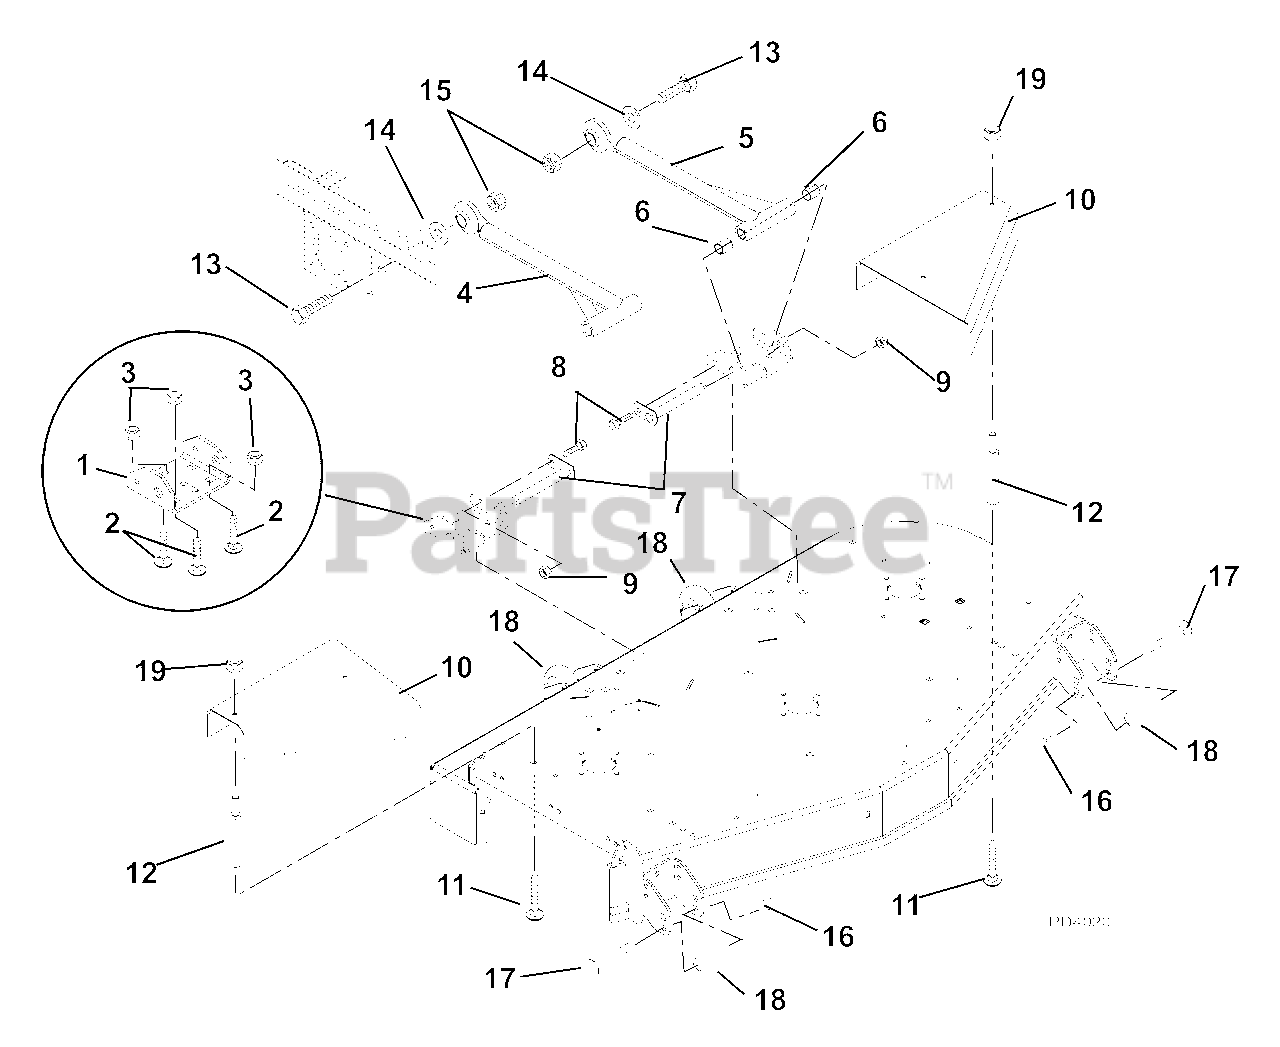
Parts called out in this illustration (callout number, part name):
1	Bracket, Mower Mounting (Rear)
2	Bolt, Round Head Square Neck .50-13 x .75 Grade 5
3	Nut, Locking Center Jam .50-13
4	Assembly, Mower Mounting
5	Mower Mounting Arm
6	Bearing, .75 x .875 x 1.00
7	Weldment, Mower Mounting Pin
8	Bolt-Hex .380-16 x .88
9	Nut, Nyloc Flange 3/8-16
10	Guard, Pulley
11	Bolt, Round Head Square Neck .31-18 x .75
12	Standoff. 2.75 x 5/16-18
13	Bolt, Hex .875-9 x 3.00
14	Bushing, Sleeve .875 x 1.250 x .531
15	Nut, Locking Center .875-9
16	Nut, Nyloc Flange .50-13
17	Bolt, Round Head Square Neck .50-13 x 5.00 Grade 2
18	Wheel, 3 x 5
19	Nut, Nyloc Flange 3/8-18
